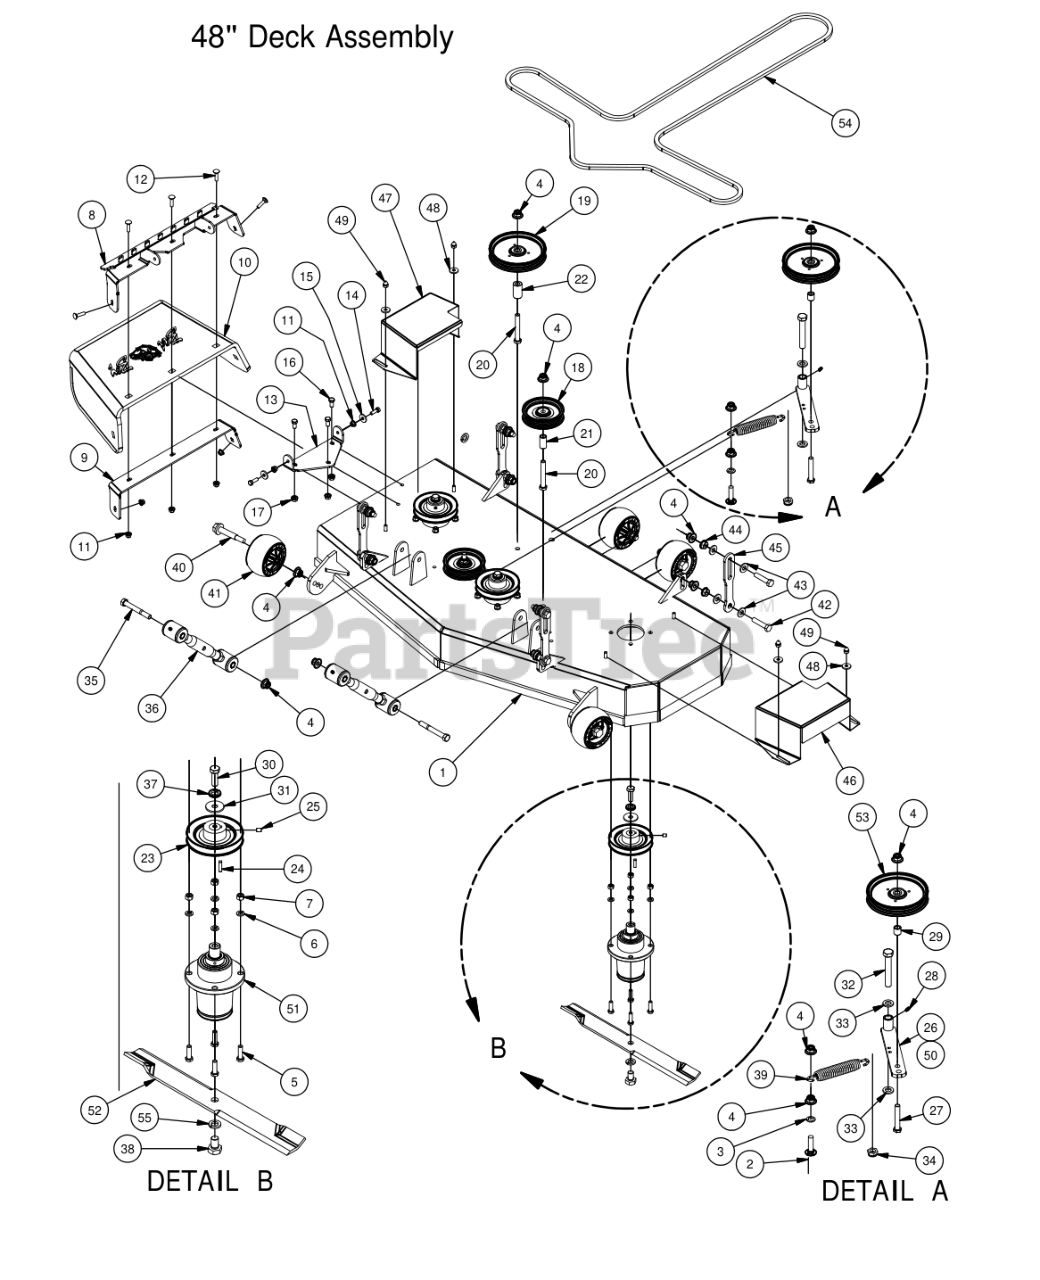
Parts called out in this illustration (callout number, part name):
1	48" Compact Outlaw Deck-Welded Shell
2	1/2 x 2" Carriage Bolt
3	.517 Square Hole Round Washer
4	1/2-13 Nylon Flange Nut
5	3/8" x 1 1/4" Hex Bolt
6	3/8" Lock Washer
7	3/8" Hex Nut
8	Discharge Upper Chute Bracket
9	Discharge Lower Chute Bracket
10	Rubber Discharge Chute
11	5/16" Nylon Flange Nut
12	5/16" x 1 1/4" Carriage Bolt
13	Discharge Chute Hanger (Deck Mounted)
14	5/16" x 1" Bolt
15	.360 ID Plastic Washer
16	3/8" x 3/4" Hex Bolt
17	3/8" Flange Nut
18	4 3/4" Idler Pulley
19	5-3/4 Idler Pulley
20	1/2 x 3 1/2 Flange Bolt Grade 8
21	.502 ID X.750 OD X 1.500 Long Spacer
22	1 3/4" Pulley Spacer
23	5" Spindle Deck Pulley
24	1/4" x 1" Key
25	5/16 Set Screw
26	Deck Idler
27	1/2-13 x GR 5 Hex Bolt Zinc
28	1/4" Press in Grease Fitting
29	Spacer 3/4 OD x 1/2 ID x 3\4 Length
30	1/2"-20 x 1 1/2 - Grade 5 Fine Thread Bolt
31	1/2 Belleville Washer
32	5/8" x 4" Hex Bolt
33	.630 ID X 1.122 OD X .142 THK Flat Washer Nylon
34	5/8" Nylock (1/2 Jam)
35	1/2" x 4" Bolt (Grade 8)
36	Turnbuckle
37	1/2" Lock Washer Zinc
38	5/8" x 1 1/2" Grade 8 Hex Bolt (Fine)
39	2015 Deck Idler Spring Outlaws
40	Deck Wheel Bolt
41	Anti-Scalp Rollers
42	1/2-13X 2-1/4 GR Hex Bolts
43	.505 Nylon Spacer
44	1/2" Flange Nut
45	Deck_Hanging_Tab longer
46	Pulley Cover Compact Outlaw-Left
47	Pulley Cover Compact Outlaw-Right
48	.360 ID Plastic Washer-Black
49	Acorn nut-pulley Cover
50	Idler Arm Assembly (Parts 4,26,27,28,29,53)
51	Spindle Assembly
52	Fusion Blade
53	5-3/4 Idler Pulley
54	48 Deck Belt
55	5/8" Lock Washer
